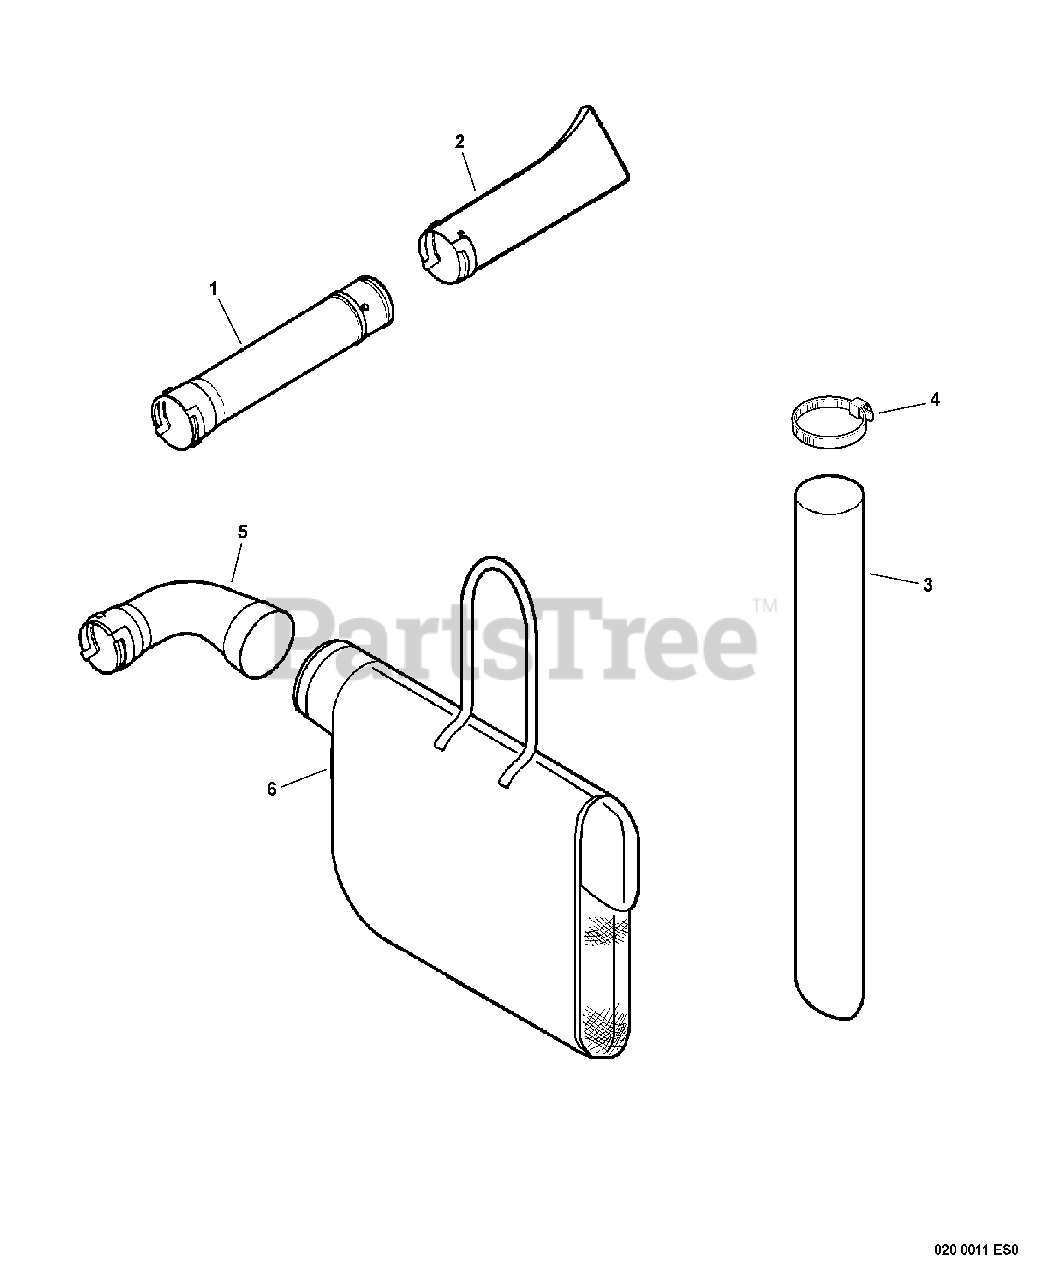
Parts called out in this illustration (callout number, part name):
1	TUBE, BLOWER - STRAIGHT
2	TUBE, BLOWER - NOZZLE
3	TUBE, VACUUM
6	BAG, DUST
